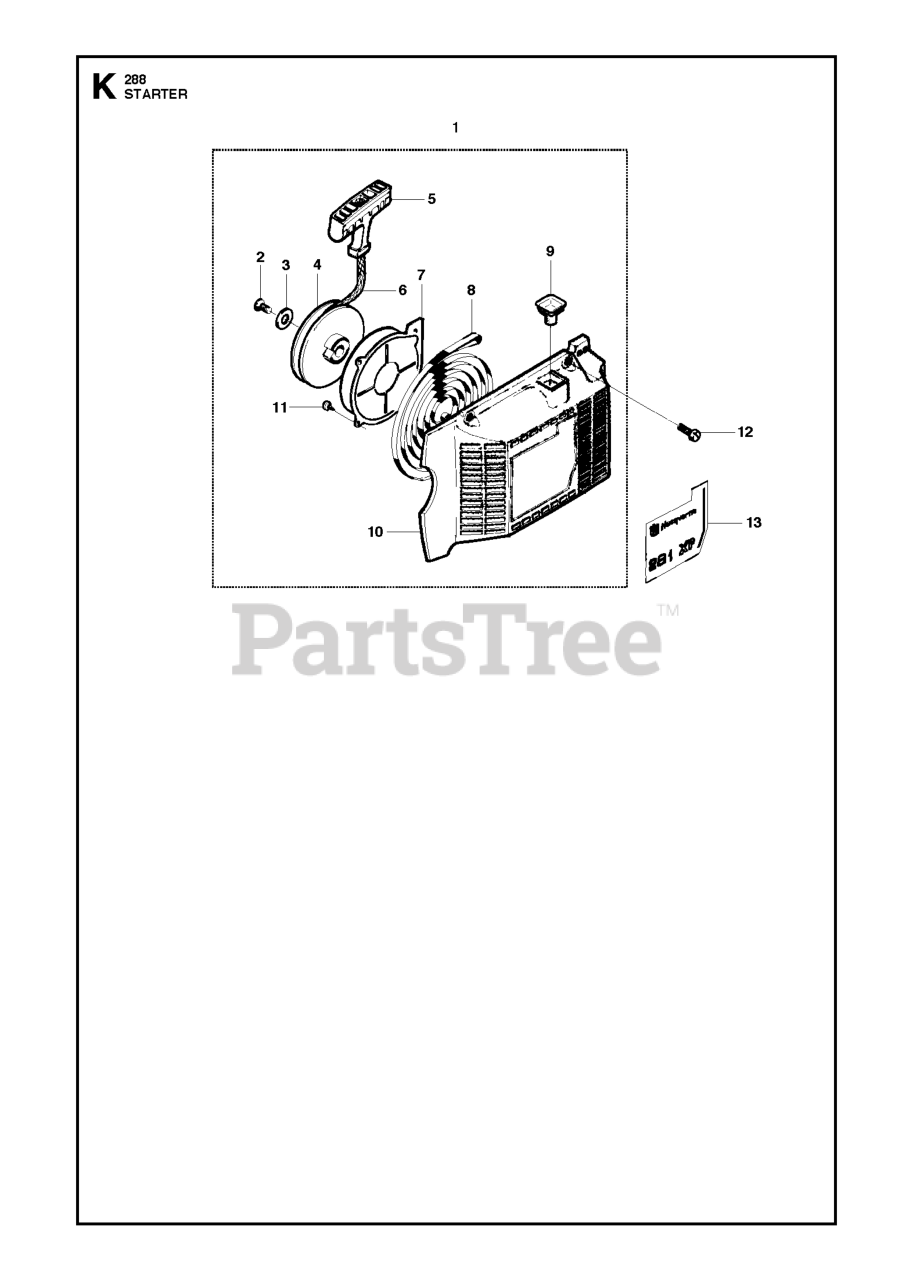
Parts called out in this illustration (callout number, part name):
1	STARTER ASS'Y
4	STARTER PULLEY
5	STARTER HANDLE
6	STARTER ROPE
8	RECOIL SPRING
10	STARTER/HOUSING
13	DECAL 288XP
